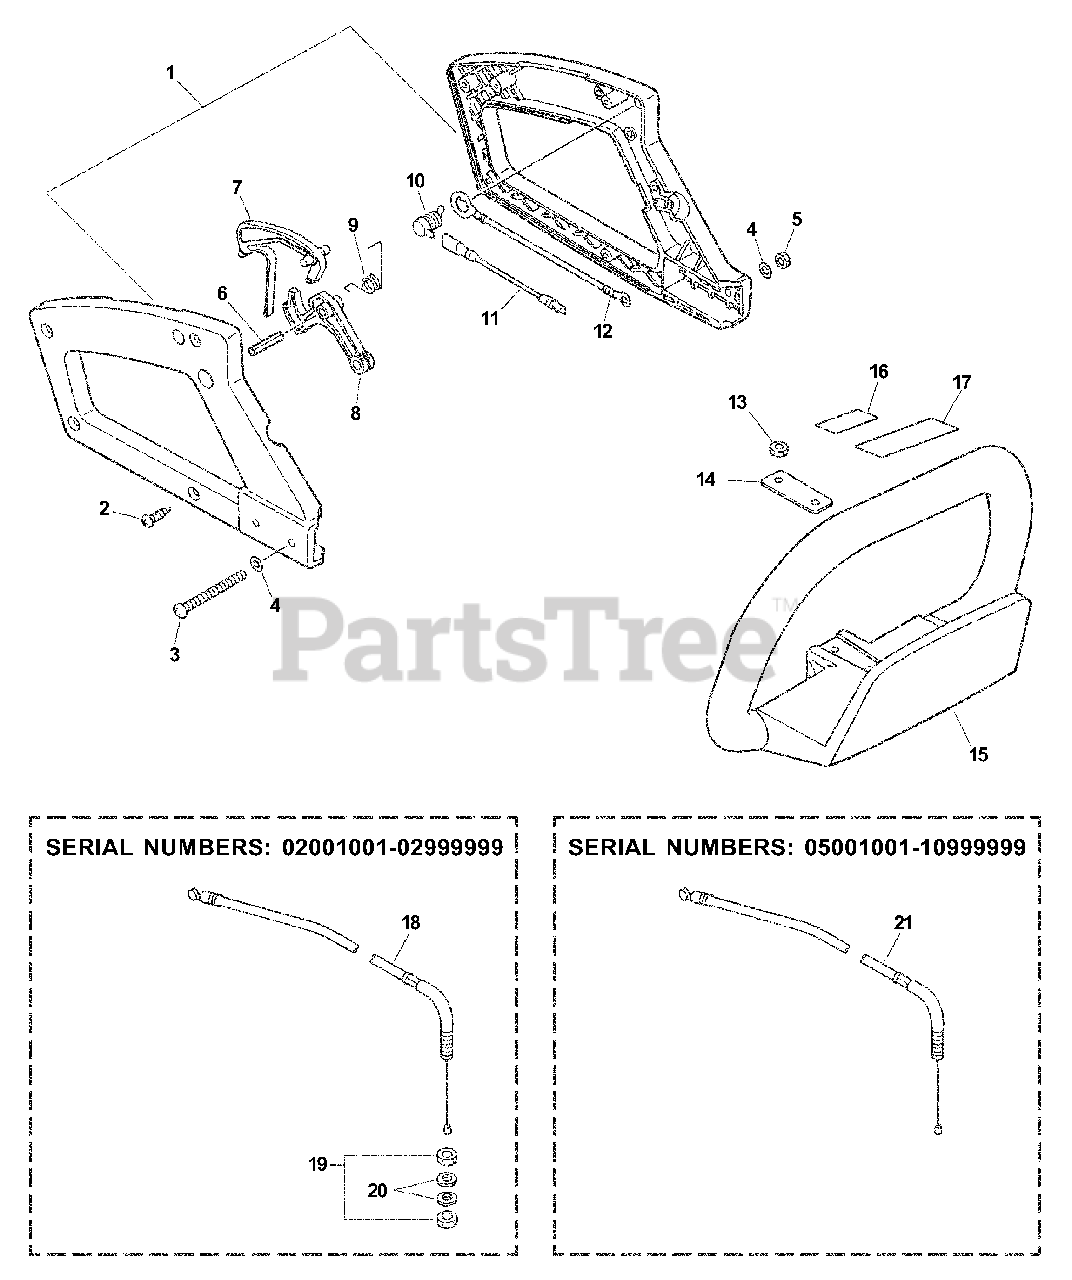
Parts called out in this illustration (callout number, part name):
1	HANDLE ASSY - REAR
2	SCREW - 4X16
3	SCREW - 5X40
4	WASHER - 5
5	LOCKNUT - 5
6	PIN - SPRING -- 5X25
7	LOCKOUT, THROTTLE
8	TRIGGER, THROTTLE
9	SPRING, TRIGGER
10	IGNITION SWITCH ASSY
11	LEAD - IGNITION
12	LEAD - GROUND
13	LOCKNUT - 5
15	HANDLE - FRONT
16	LABEL - CAUTION
17	LABEL - CAUTION
18	CABLE, THROTTLE
20	WASHER - 6
21	CABLE, THROTTLE
